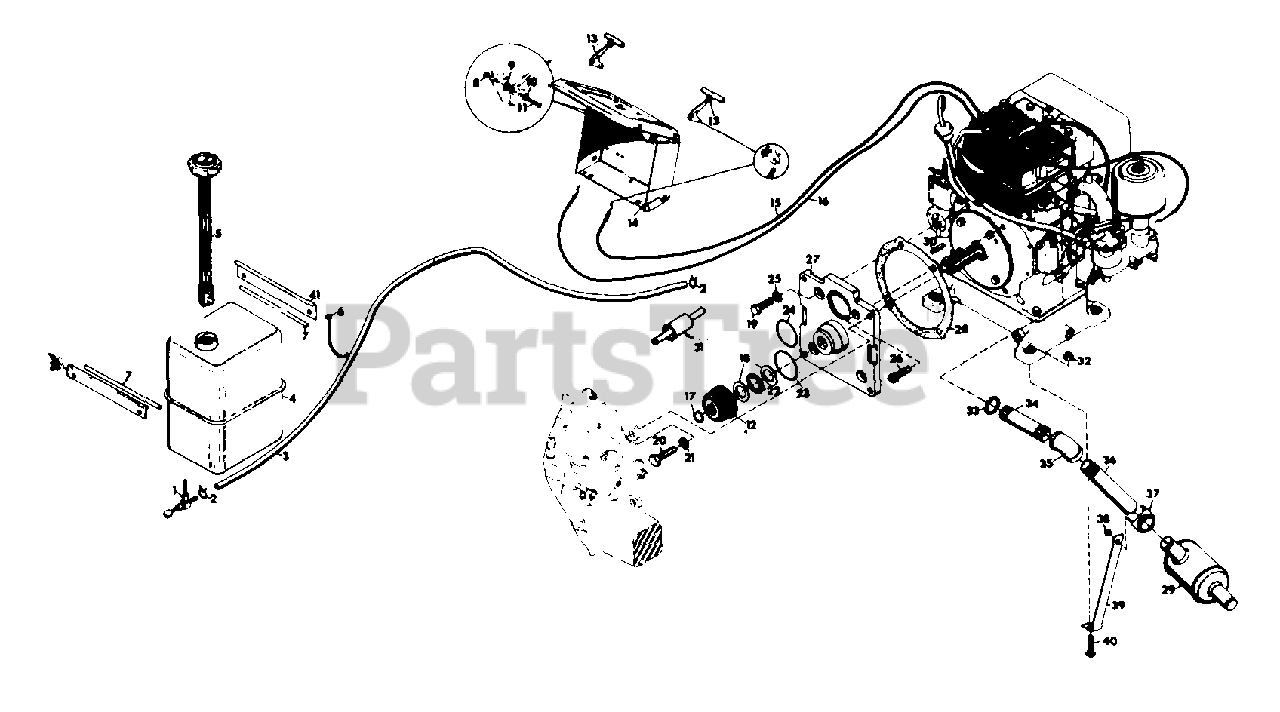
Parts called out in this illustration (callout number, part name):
1	VALVE, FUEL 90 DEG. REVERSE FLOW
2	CLAMP, FUEL HOSE
3	LINE, FUEL
4	TANK, FUEL
5	GAUGE, GAS
6	TIE, CABLE
7	MOULDING
8	NUT, LOCK 1/4-28
9	WASHER, FRICTION
10	WASHER, SPRING
11	BOLT, HEX 1/4-28X.75
12	GEAR, SPUR AND BEVEL, INPUT
13	ASSEMBLY, KNOB AND LEVER
14	PANEL, INSTRUMENT
15	ASSEMBLY, CHOKE CONDUIT
16	ASSEMBLY, THROTTLE CONDUIT
17	RING, RETAINING 1.125 SHAFT
18	RACE, BEARING THRUST 1.127X1.740X.060
19	BOLT, HEX 7/16-14X1.125
20	BOLT, HEX 1/2-13X1.25
21	WASHER FLAT .500X1.062X.095
22	BEARING, THRUST 1.127X1.740X.078
23	O-RING, 3.000X3.188X.094
24	O-RING, 2.500X2.750X.125
25	WASHER, LOCK 7/16 SP HEAVY
26	SCREW, CAP 7/16-14X1.0 SOCKET HEAD
27	ADAPTOR, ENGINE
28	GASKET, ADAPTOR
29	MUFFLER, EXHAUST
30	KEY, SQUARE .250X1.250
31	FUEL FILTER
32	NUT, LOCK 3/8-16
33	NUT, CONDUIT 1" PIPE
34	NIPPLE, PIPE 1X6
35	PIPE, 1 IN. ELBOW
36	NIPPLE, PIPE 1"X8.4" SPECIAL
37	CLAMP, MUFFLER
38	NUT, HEX 5/16-24
39	SUPPORT, EXHAUST
40	BOLT, HEX 3/8-16X1.125
41	BRACKET, REAR TANK
42	BRACKET, FORWARD TANK
43	ENGINE, 16 HP B&S
